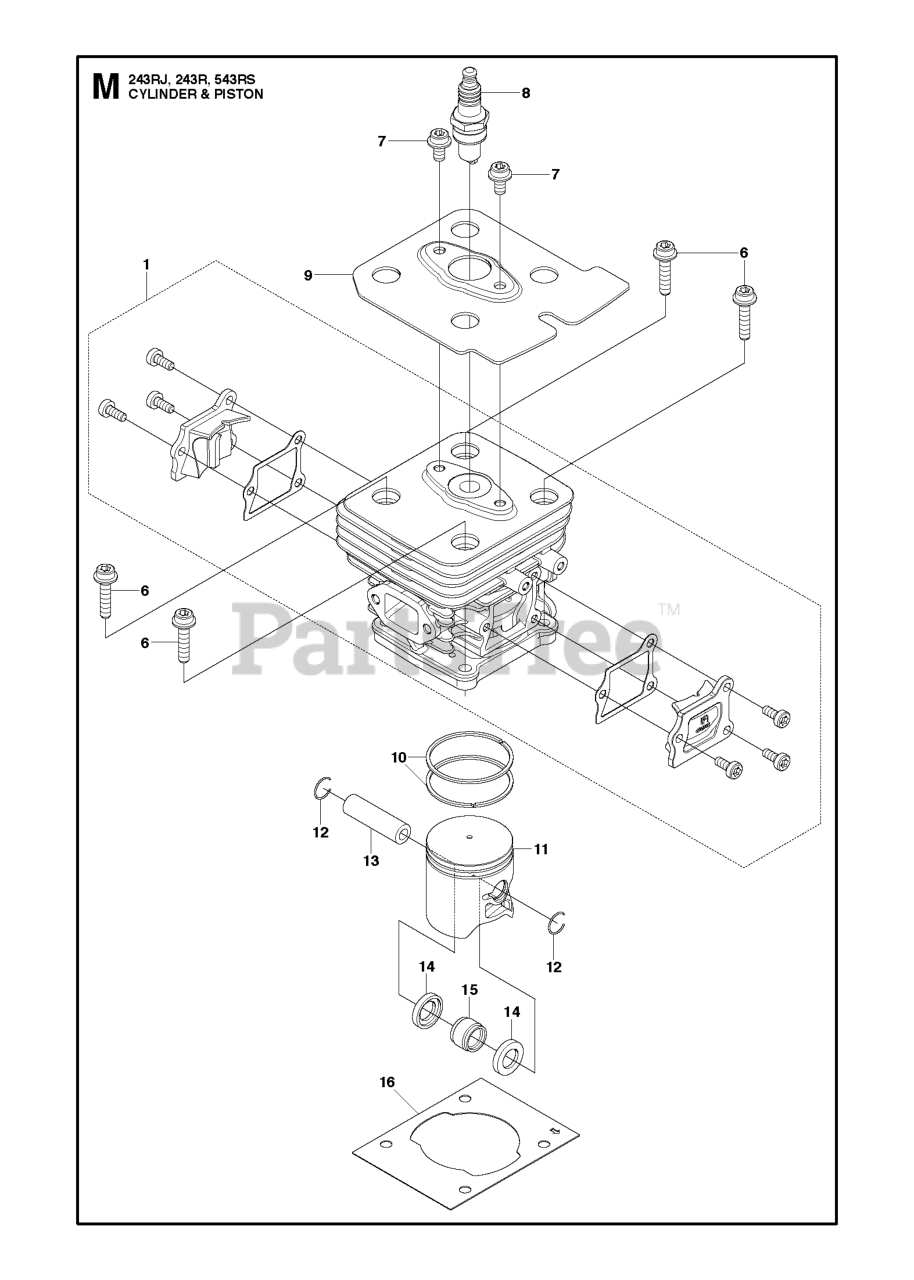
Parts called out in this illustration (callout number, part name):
1	CYLINDER-COMP 848GG01211
1	CYLINDER COMP
7	BOLT (RPLS T495051010-11)
8	SPARK PLUG CMR7H-10
9	PLATE
10	RING PISTON
11	PISTON 848GG041A0
11	PISTON
15	ROLLER BEARING
